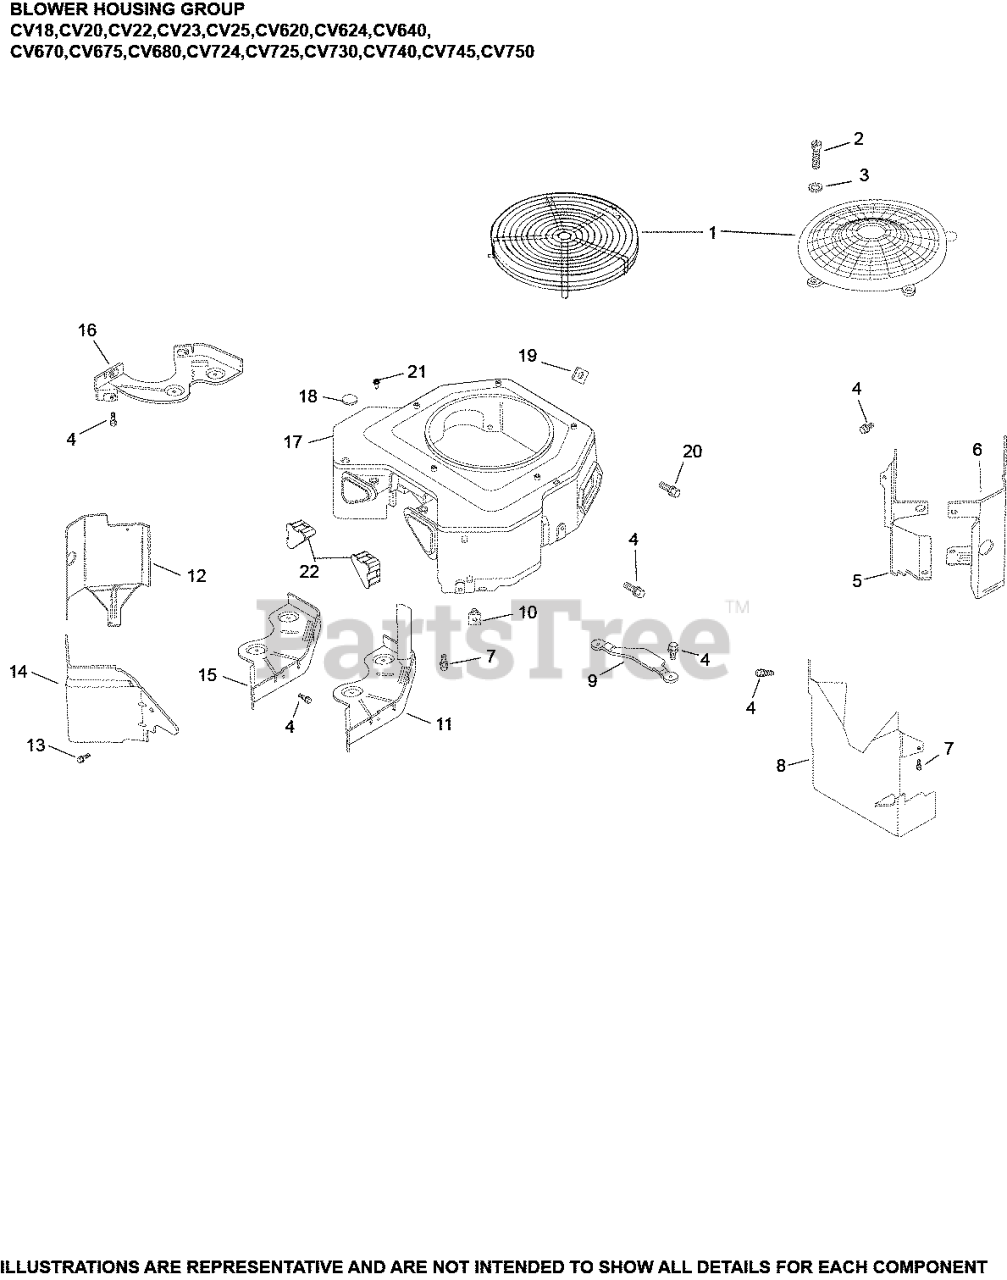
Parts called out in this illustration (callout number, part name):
4	SCREW, THREAD FORMING
5	BAFFLE, VALLEY #1 CYLINDER USE 24 063 114-S
6	KIT, CYL BAFFEL #2 SIDE
12	KIT, CYL BAFFEL #1 SIDE
13	SCREW, THREAD FORMING
14	BAFFLE, VALLEY #2 CYLINDER
15	KIT, BACKING PLATE
17	HOUSING, BLOWER
22	COVER, BLOWER HOUSING USE 24 096 160-S
